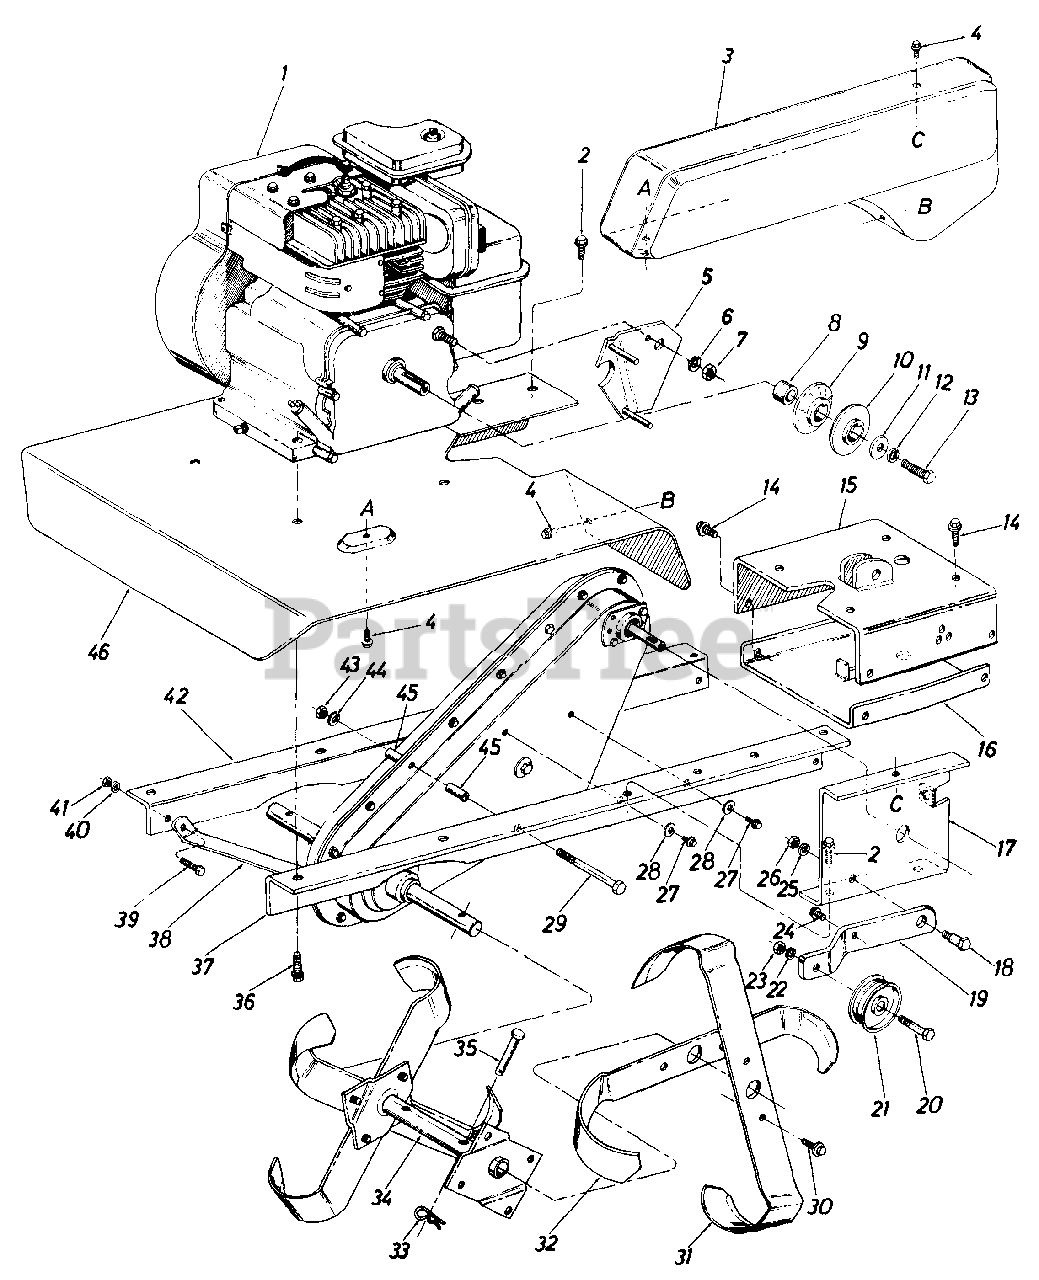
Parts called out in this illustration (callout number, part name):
1	Engine
2	Hex Wash. Hd. Self-Tap Scr. 5/16-24 x .50" Lg.
3	Belt Cover
4	Hex Wash. Hd. Self-Tap Scr. 1/4-20 x .50" Lg.
5	Belt Keeper Brkt. Ass'y.
6	L-Wash. 1/4" I.D.
7	Hex Wash. Hd. Self-Tap Scr. 1/4-20 x .62" Lg.
8	Spacer
9	Pulley Half
10	Pulley Half
11	Fl-Wash. 3/8" I.D. x 1.25" O.D. x .100
12	L-Wash. 3/8" Scr.
13	Hex Scr. 3/8-24 x 1.00" Lg.
14	Hex Wash. Hd. Self-Tap Scr. 3/8-24 x 7/8" Lg.
15	Handle Mounting Brkt. Ass'y.
16	U-Channel Brkt. Ass'y.
17	Idler Mounting Brkt.
18	Shld. Bolt
19	Idler Bracket
20	Hex Scr. 3/8-16 x 1.50" Lg.
21	Idler Pulley
22	L-Wash. 3/8" Scr.
23	Hex Nut 3/8-16 Thd.
24	Hex Wash. Hd. Self-Tap Scr. 5/16-18 x .75" Lg.
25	L-Wash. 3/8" Scr.
26	Hex Nut 3/8-16 Thd.
27	Hex Wash. Hd. Self-Tap Scr. 1/4-20 x .50" Lg.
28	Belleville Wash. .26 I.D. x .7 O.D. x .060
29	Hex Scr. 5/16-18 x 2.75" Lg.
30	Hex Wash. Self-Tap Scr. 5/16-24 x .50" Lg.
31	Tine Blade - L.H.
32	Tine Blade - R.H.
33	Hairpin Cotter
34	Tine Adapter Ass'y.
35	Clevis Pin
36	Hex Wash. Hd. Self-Tap Scr. 3/8-16 x 1.25" Lg.
37	Frame Rail - L.H.
38	Front Brace Brkt.
39	Hex Scr. 5/16-18 x .75" Lg.
40	L-Wash. 5/16" Scr.
41	Hex Cent. L-Nut 5/16-18 Thd
42	Frame Rail - R.H.
43	Hex Cent. L-Nut 5/16-18 Thd
44	L-Wash. 5/16" Scr.
46	Tine Shield
